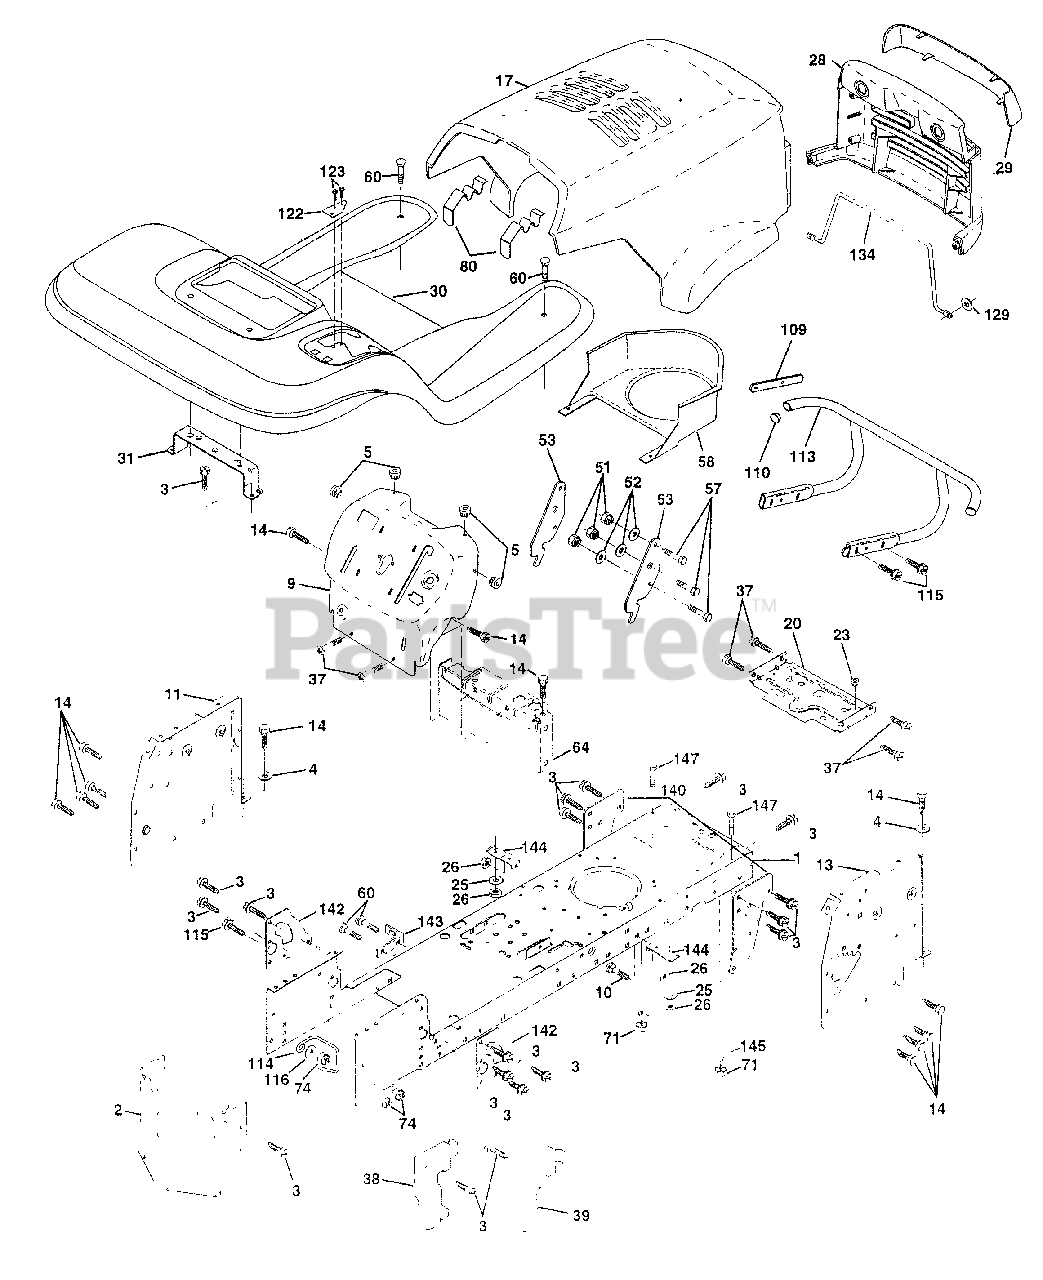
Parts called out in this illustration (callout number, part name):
1	Chassis Weldment
2	Drawbar, Stretch
3	Screw Thdrol 3/8-16x3/4 Ty-ft
4	Washer 13/32 x 3/4 x 16 Ga.
5	Bumper Hood/Dash
9	Dash Slkscr
10	Bolt Carriage 3/8-16 x 1
11	Panel Dash Lh
13	Panel Dash Rh
14	Screw Thdrol 3/8-16x1/2 Ty-tt
17	Hood LT/PL Husqvarna
20	Plate Mtg Battery Fuel Tank Fr
25	Washer 13/32 X 13/16 X 12 Ga
26	Nut Lock Hex W/Ins 3/8-16 Unc
28	Grille LT/PL Husqvarna
29	Lens LT/PL Husqvarna
30	Fender Footrest STLT Pnt
31	Bracket Support Fender
37	Screw Thdrol 6/16-18 x 1/2 TYT
38	Bracket, Asm. Pivot, L.H., Mower Rear
39	Bracket, Asm. Pivot, R.H., Mower Rear
51	Nut Lock Hex W/Ins 1/4-20
52	Washer 9/32 x 7/8 x 16 Ga.
53	Bracket Pnt. Pick off LT/PL Husqvarna
57	Bolt Hex 1/4-20 x 3/4
58	Air Duct Engine CV18
60	Bolt Rdhd Sqnk 3/8-16unc x 3/4
64	Dash Lower STLT
71	Nut Crownlock 1/4-20 Unc
74	Nut Crownlock 3/8-16 UNC
80	Latch Hood Plm Husqvarna
109	Bracket Extension Bumper
110	Plug Plastic
113	Bumper Asm.
115	Screw Thdrol 3/8-16 x 1-1/4
122	Bracket Shift STLT
129	Washer 9/32 x 5/8 x 16 Ga.
134	Rod Support Hood LT/PL Husq.
140	Bracket Suspension Front
142	Plate Reinforcement STLT
143	Bracket Swaybar Chassis
144	Bracket Pnt Footrest STLT
145	Rod Pivot Chassis/Hood
147	Bolt Hex Hd 1/4-20 Unc x 3/4
